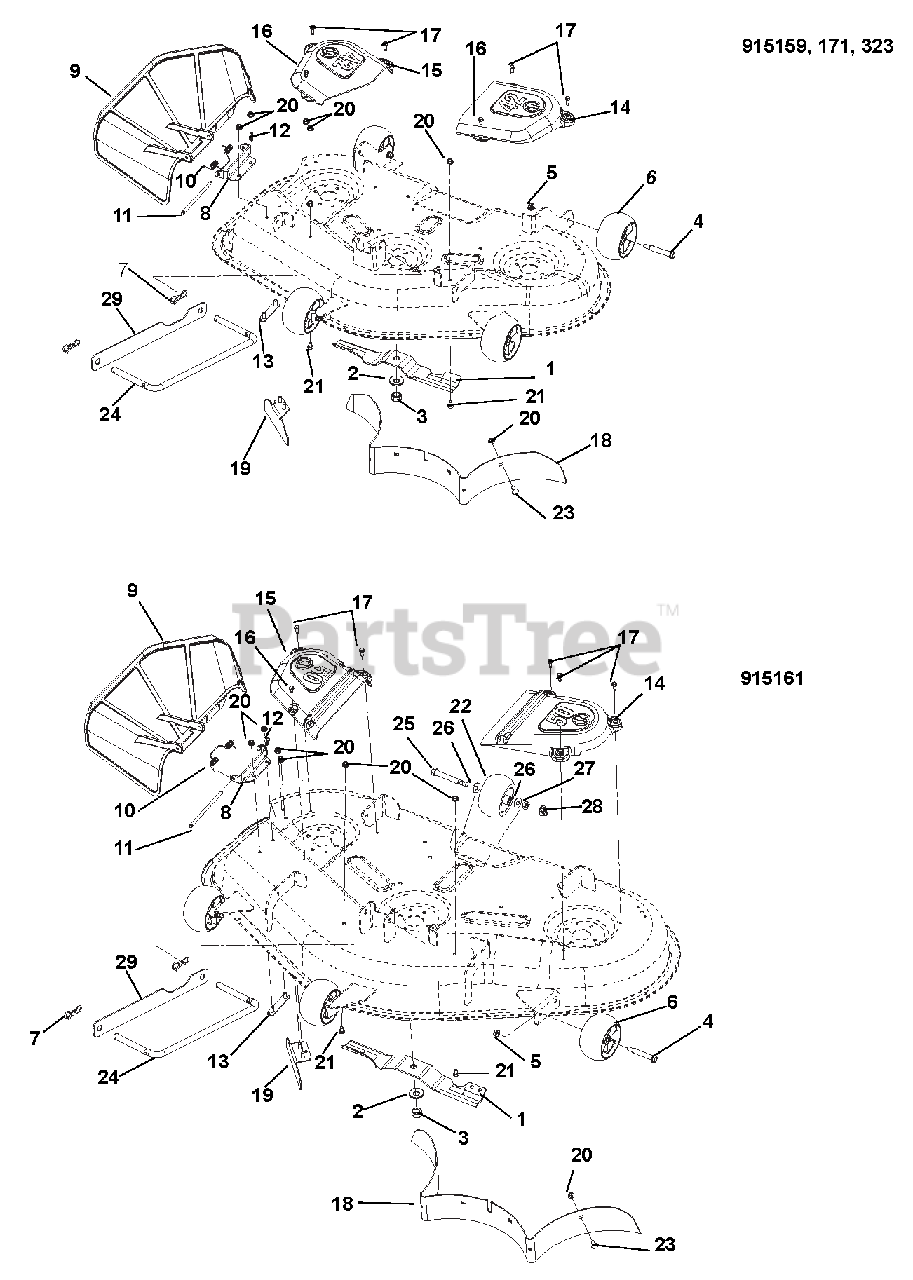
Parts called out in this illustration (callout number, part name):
1	BLADE, MOWER 14.83 (.188 THK)
1	BLADE, MOWER 17.35
2	WSHR-BLVL .669X1.535X.138
3	NUT-HEX .62-18 YWZC
4	BLT-SHLDR .38-16X2.50 HWH G5
5	@NUT-LK-TOP-FLG .38-16 YWZC
6	ANTI-SCALP WHEEL - 5X OS
7	PIN,BOW TIE LOCKING .091X1.875
8	BRKT-DISCHARGE CHUTE MOUNT 42"
8	BRKT, CHUTE MOUNT - 50"
9	CHUTE, DISCHARGE - MOLDED
10	SPRING-TORSION
11	PIN, 5/16 X 5.80"
12	PIN-HAIR INT .08X.18X1.18 YWZC
13	WMT-DISCHARGE CHUTE MT. STRAP
14	BELT COVER - LH 42"
14	BELT COVER - LH 50"
15	BELT COVER - RH 42"
15	BELT COVER - RH 50"
16	SCR-TAP .25-20X.50 HWH TR YWZ
17	SCR-TAP .25-20X.75 HWH TR YWZ
18	BAFFLE, REAR (42)
18	BAFFLE-50" STAMPED DECK REAR
19	WLDMT-BAFFLE, DISCHARGE 42"
19	BAFFLE, DEFLECTOR (50)
20	@NUT-LK-TOP-FLG .31-18 YWZC
21	@BLT-HEX .31-18X.50 GR5 YWZC
22	ROLLER
23	@BLT-RHDSSQNK .31-18X.75 G5YZ
24	WIREFORM, DRAG LINK
25	@BLT-HEX .38-16X3.50 GR5 YWZC
26	@WSHR-FL-STL.406X.812X.065 YWZ
27	@NUT-LK-CTR-JAM .375-16 YWZC
28	@NUT-LK-NYL-FLG .38-16 YWZC
29	STRAP, DRAG LINK
